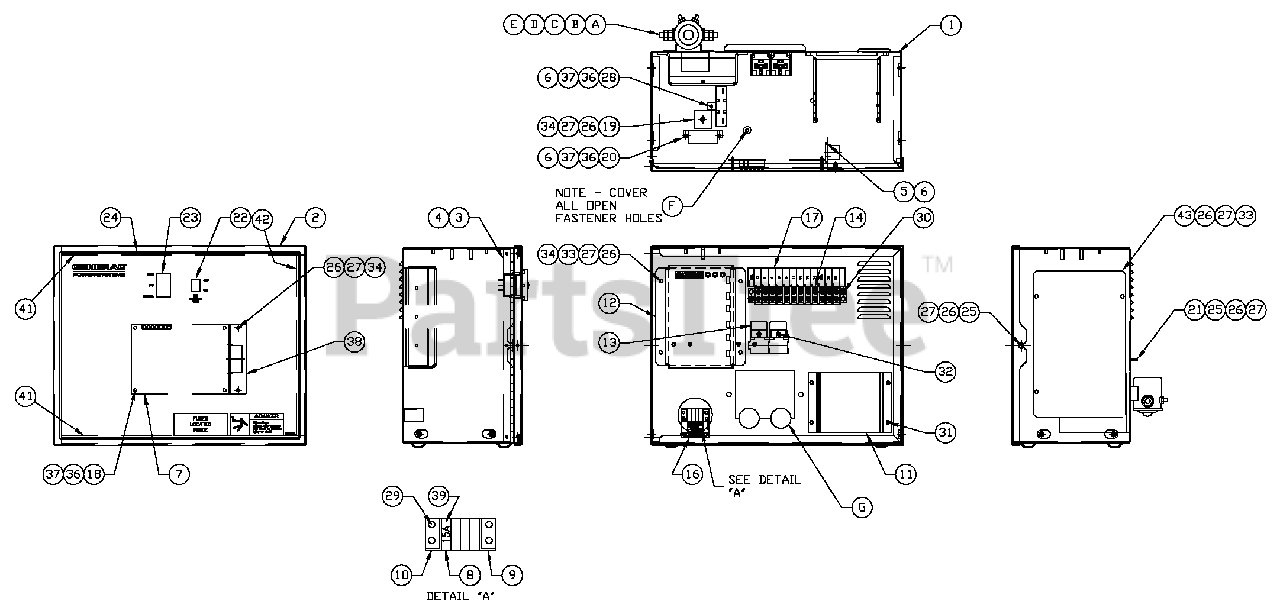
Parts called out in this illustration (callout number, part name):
1	ENCL HSB CONTROL PANEL
2	COVER CONTROL PANEL
3	HINGE CONTINUOUS H'PNL
4	RIVET POP .125 X .275 SS
5	SCREW PHM M3'0.5 X 10MM
6	WASHER FLAT M3
7	ASSY PCB CPL CTRLR 3600 RPM
8	HOLDER FUSE WICKMANN 178.6150
9	ADPTR RH SIDE WICKMAN 178.6191
10	ADPTR LH SIDE WICKMAN 178.6192
11	ASSY PCB 2AMP 12V UL BATT CHGR
12	ASSY VOLTAGE REGULATOR 60HZ
13	RELAY 12VDC C FORM W/DIODE
14	BLOCK TERM 20A 12 X 6 X 1100V
16	DECAL CPL CONTROL PANEL FUSES
17	DECAL CPL 3.9L TB1
18	SPACER 9.5H 3.2 ID
19	DIO BRIDGE 25A 600V
20	CB 4 X 1 ETA 46'500'P
21	PLATE HARNESS CLAMP
22	SWITCH RKR DPST 125V SPD
23	SWITCH RKR DPDT ON'OFF'ON
24	DECAL CONTROL HSB
25	SCREW HHPM M5'0.8 X 12
26	WASHER FLAT M5
27	WASHER LOCK M5
28	RES WW 25R 5% 25W QK CONN
29	SCREW PHTT M3.5'0.6 X 10
30	SCREW PHTT M3.5'0.6 X 16
31	SCREW PHTT M4'0.7 X 12 ZYC
32	SCREW PHTT M4'0.7 X 10 ZYC
33	SCREW PPHM M5'0.8 X 12 ZNC
34	NUT HEX M5'0.8 G8 CLEAR ZINC
36	WASHER LOCK M3
37	NUT HEX M3'0.5 G8 YEL CHR
38	SUPPORT ANGLE PCB
39	FUSE ATO TYPE 15 AMP (BLUE)
41	SEAL COVER 3.18 X 12.7 X 382
42	SEAL COVER 3.18 X 12.7 X 283
43	PLATE COVER H PANEL
A	RELAY SOLENOID 12VDC PNL MNT
B	SCREW HHC 1/4'20 X 3/4 G5
C	WASHER FLAT 1/4'M6 ZINC
D	WASHER LOCK M6'1/4
E	NUT HEX 1/4'20 STEEL
F	SEAL WEATHER .45" DIA
